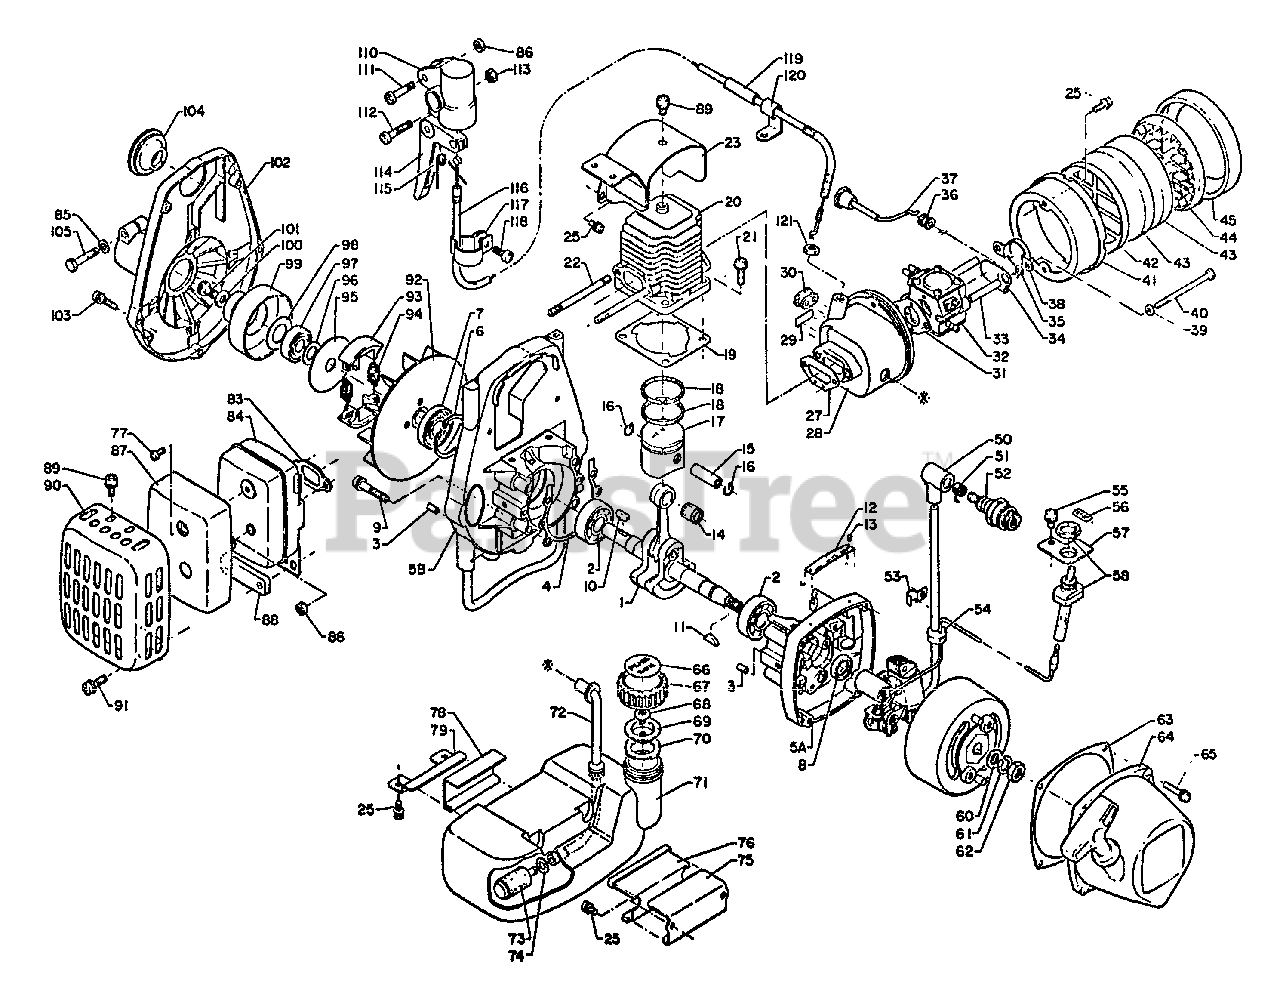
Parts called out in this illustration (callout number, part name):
1	CRANKSHAFT ASSY
2	BEARING, BALL - 6201
3	PIN - LOCATING
4	GASKET, CRANKCASE
5	CRANKCASE KIT
5A	CRANKCASE KIT
5B	CRANKCASE KIT
6	RING, RETAINING - 32
7	SEAL, OIL
8	SEAL, OIL
9	SCREW - 5X28
12	PLATE, MODEL
13	RIVET
14	BEARING, NEEDLE
15	PIN, PISTON
16	RING, RETAINING
17	PISTON
18	RING, PISTON
19	GASKET, CYLINDER
20	CYLINDER
21	SCREW - 5X16
22	STUD
23	SHIELD, CYLINDER
25	SCREW - 4X10
27	GASKET, INTAKE
28	CASE, CARBURETOR
29	LABEL - CAUTION
31	GASKET, INTAKE
32	CARBURETOR
33	SPACER
34	SHUTTER, CHOKE
35	WASHER
37	ROD, CHOKE
38	PLATE, PREVENT
41	CASE, AIR FILTER
42	RETAINER, AIR FILTER
43	FILTER, AIR
44	COVER, AIR FILTER
45	COVER, AIR FILTER
50	CAP, SPARK PLUG
51	TERMINAL, SPARK PLUG CAP
52	SPARK PLUG -- BM-6A
53	CLAMP
55	SCREW - 5X12
56	LABEL - STOP
57	BRACKET, SWITCH
58	IGNITION SWITCH ASSY
61	LOCKWASHER - 8
63	GASKET, STARTER
64	STARTER ASSY
65	SCREW - 4X20
66	LABEL - FUEL MIX
67	CAP
69	HOLDER, VENT
70	GASKET, CAP
71	TANK, FUEL
72	PIPE - FUEL
73	FILTER, FUEL
74	WASHER - 6
75	BRACKET, FUEL TANK
76	CUSHION, FUEL TANK
78	CUSHION, FUEL TANK
79	BRACKET, FUEL TANK
83	GASKET, EXHAUST
84	MUFFLER
85	WASHER - 5
86	LOCKNUT - 5
87	INSULATOR
88	SPACER
89	SCREW - 5X10
90	COVER, MUFFLER
91	SCREW - 5X16
92	FAN
93	SHOE, CLUTCH
94	SPRING, CLUTCH
95	PLATE, CLUTCH
96	WASHER, CLUTCH
97	BEARING, BALL - 6000
98	WASHER, CLUTCH
99	DRUM, CLUTCH
100	WASHER - 6
101	SCREW - 6X10
102	CASE, FAN
103	SCREW - 4X18
104	SEAL, DUST
105	BOLT - 5X25
110	BRACKET, TRIGGER
111	SCREW - 5X30
112	SCREW - 5X28
114	TRIGGER, THROTTLE
115	SPRING, TRIGGER
116	CABLE, THROTTLE
118	SCREW - 5X10
120	CLAMP
